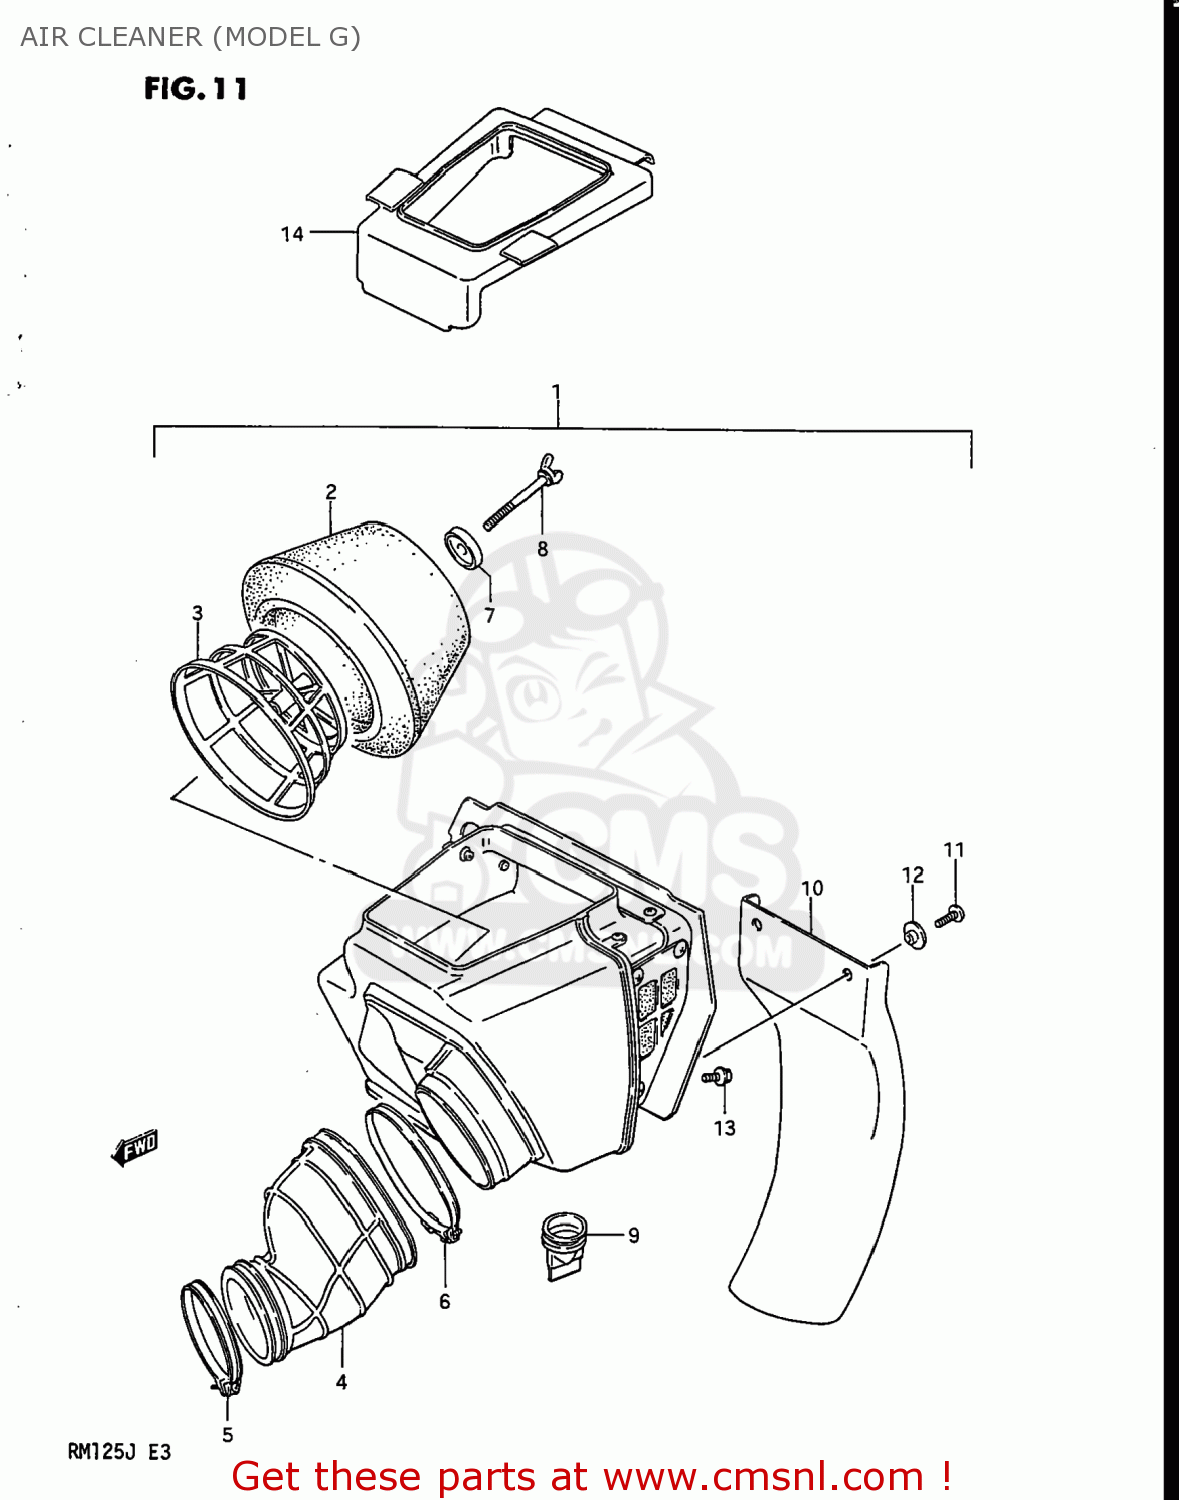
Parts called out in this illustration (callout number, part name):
1	CLEANER ASSEMBLY,AIR
2	FILTER
3	HOLDER,FILTER
4	TUBE,AIR CLEANER OUTLET
5	CLAMP
6	CLAMP
7	WASHER,AIR CLEANER
8	BOLT,WING
9	HOSE,AIR CLEANER DRAIN
10	GUARD,MUD
11	SCREW 6X12
12	COLLAR
13	BOLT
14	GUARD,MUD
